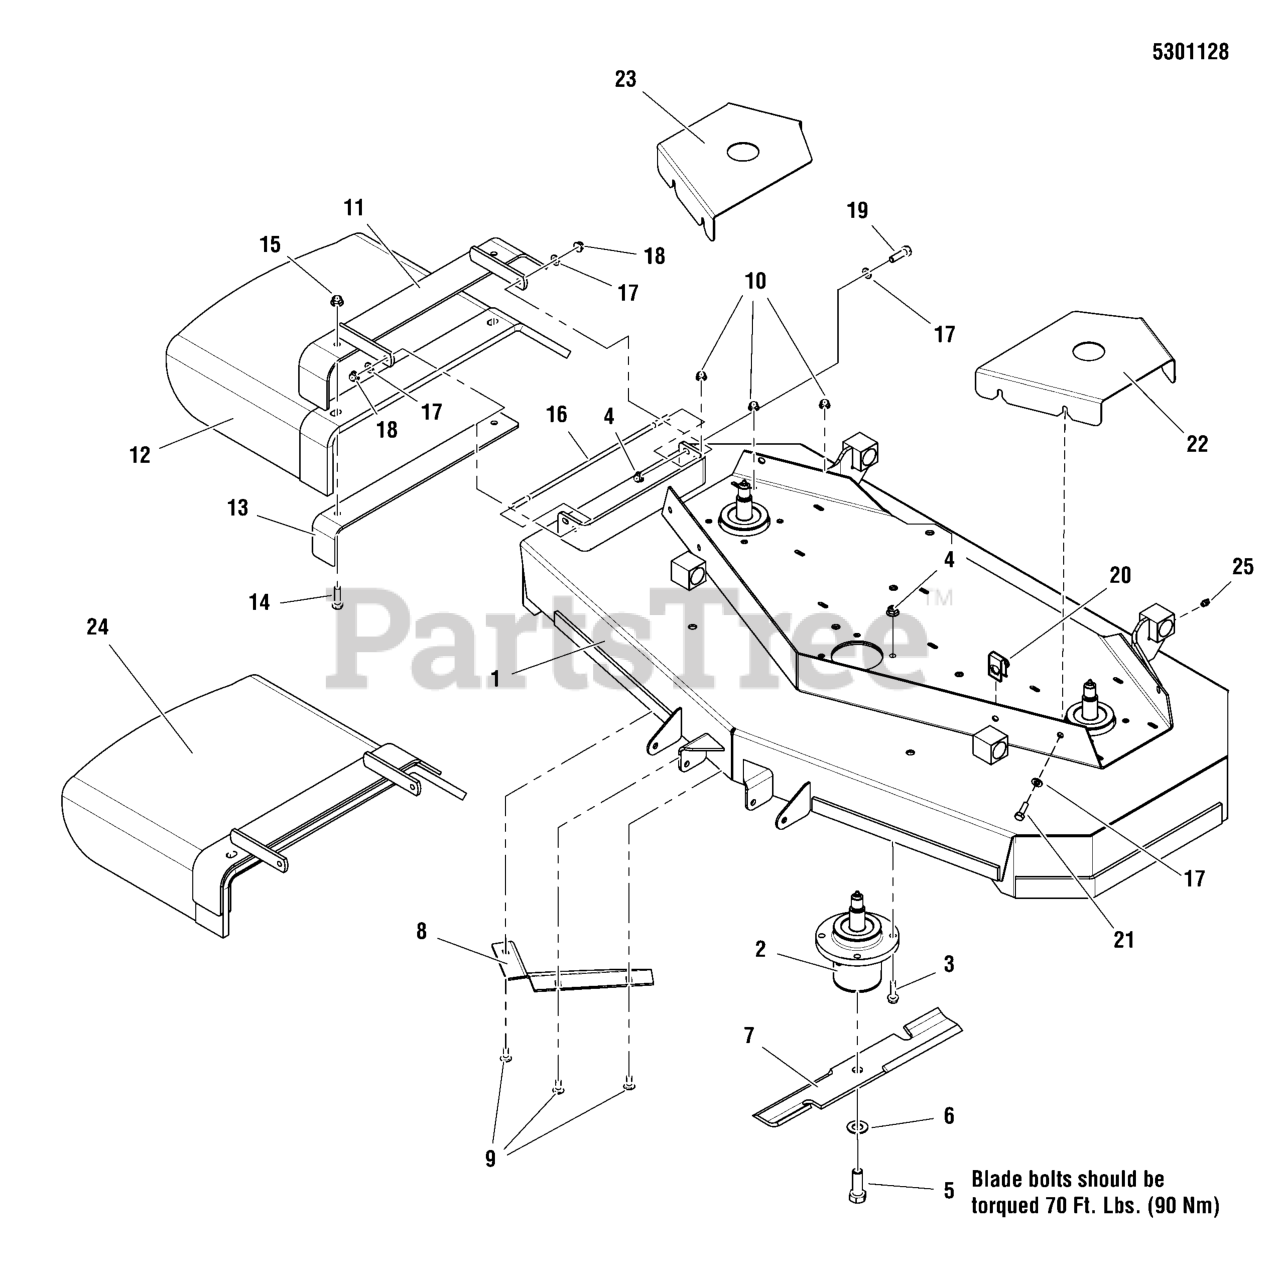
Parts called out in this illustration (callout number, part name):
1	DECK SHELL W/ DECALS, 48" - SW20
2	ASSM, SPINDLE, LOW PROFILE
3	BOLT, 5/16-18 X 1 1/4 FLANGE
4	NUT, 5/16-18 HEX NYLOCK FLANGE
5	BOLT, 5/8-11 X 1-3/4" GD8
6	WASHER, 5/8 USS
7	BLADE SET, 48 DECK (SET OF 3 BLADES)
8	WELD, DISCHARGE BAFFLE, 48" - BLK
9	BOLT, 5/16-18 X 3/4", CARRIAGE
10	NUT, 5/16-18 HEX NYLOCK FLANGE
11	WELD, MOUNT, DISCHARGE CHUTE - BLK
12	CHUTE, DISCHARGE, RUBBER, BENT, 44/48/52 (SV)
13	SUPPORT,DISCHARGE CHUTE - BLK
14	BOLT, 3/8-16 X 1-1/2" GD5 CZ
15	NUT, 3/8-16 HEX NYLOCK FLANGE
16	ROD, BRAKE LINKAGE
17	WASHER, 5/16" SAE
18	NUT, 5/16-24 HEX NYLON LOCK
19	BOLT, 5/16-18 X 3/4 GD5
20	BODY CLIP, 5/16-18-7GA MATERIAL
21	BOLT, 5/16-18 X 1 GD5 YZ
22	GUARD, DECK, 48, DDS, LH - RED
23	GUARD, DECK, 48, DDS, RH - RED
24	KIT, DISCHARGE CHUTE, 44/48/52
25	GREASE FITTING, 1/4-28 STRAIGHT
